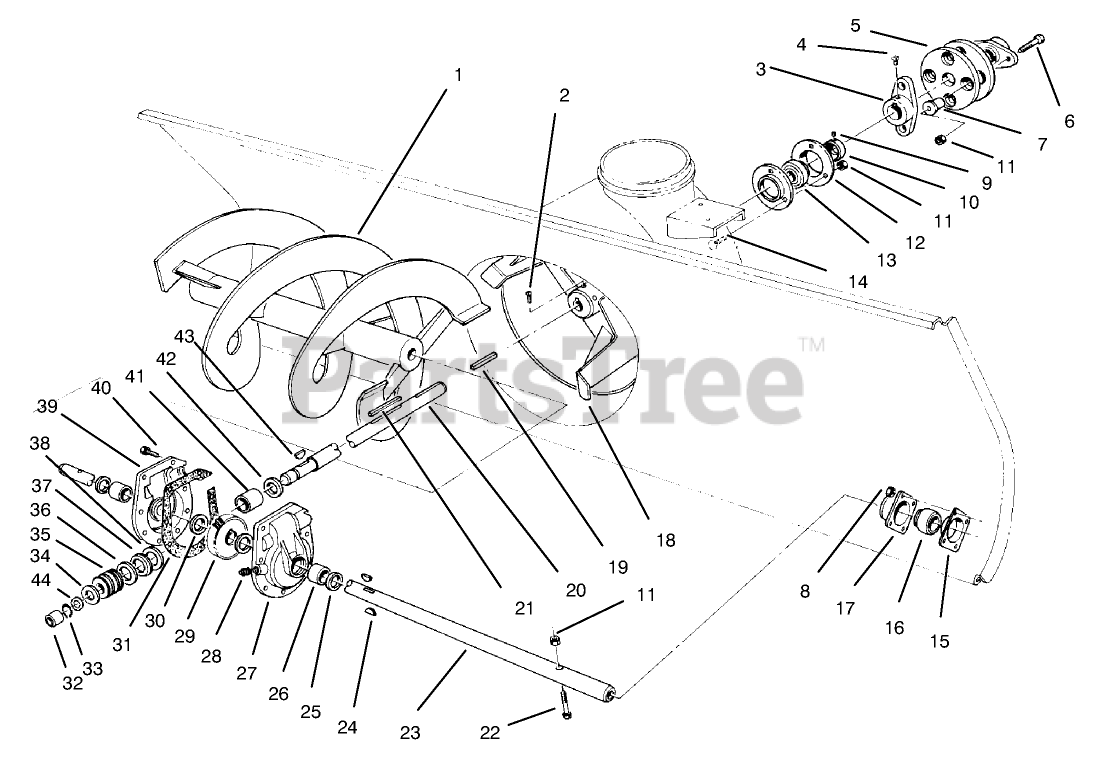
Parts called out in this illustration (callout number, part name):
1	Auger RH
2	SCREW-SET, SQH
3	HUB WA (KEY) R
4	SCREW-SET
5	COUPLING-RUBBER
6	SCREW-HH
7	SPACER-COUPLING, RUBBER
8	NUT-LOCK, NI
9	SCREW-HSH
10	EXT LOCKING COLLAR
11	NUT-LOCK, NI
12	BRG FLANGE
13	BALL BRG W/COLLAR
14	BOLT-CARR
15	BEARING-FLANGE, REAR
16	BEARING
17	BEARING-FLANGE, FRONT
18	IMPELLER ASM
19	KEY-SQUARE
20	IMPELLER SHAFT
22	SCREW-HH
23	SHAFT-AUGER
24	KEY-WOODRUFF
25	SEAL-OIL
26	BUSHING
27	Gear Case & Bushing Assy. (Incl. Ref. #25 & 26)
28	PLUG-PIPE, SQH
29	GEAR-WORM, 27T
30	WASHER-THRUST
31	GASKET-GEAR BOX
32	BUSHING
33	Ring-Snap
34	WASHER-THRUST
36	THRUST-WASHER
37	BEARING-THRUST
38	WASHER-THRUST
39	Gear Case & Bushing Assy. (Incl. Ref. #25 & 26)
40	SCREW-TAPTITE
41	BUSHING-SPECIAL
42	RING-QUAD
43	KEY-WOODRUFF
44	WASHER-SHIM
